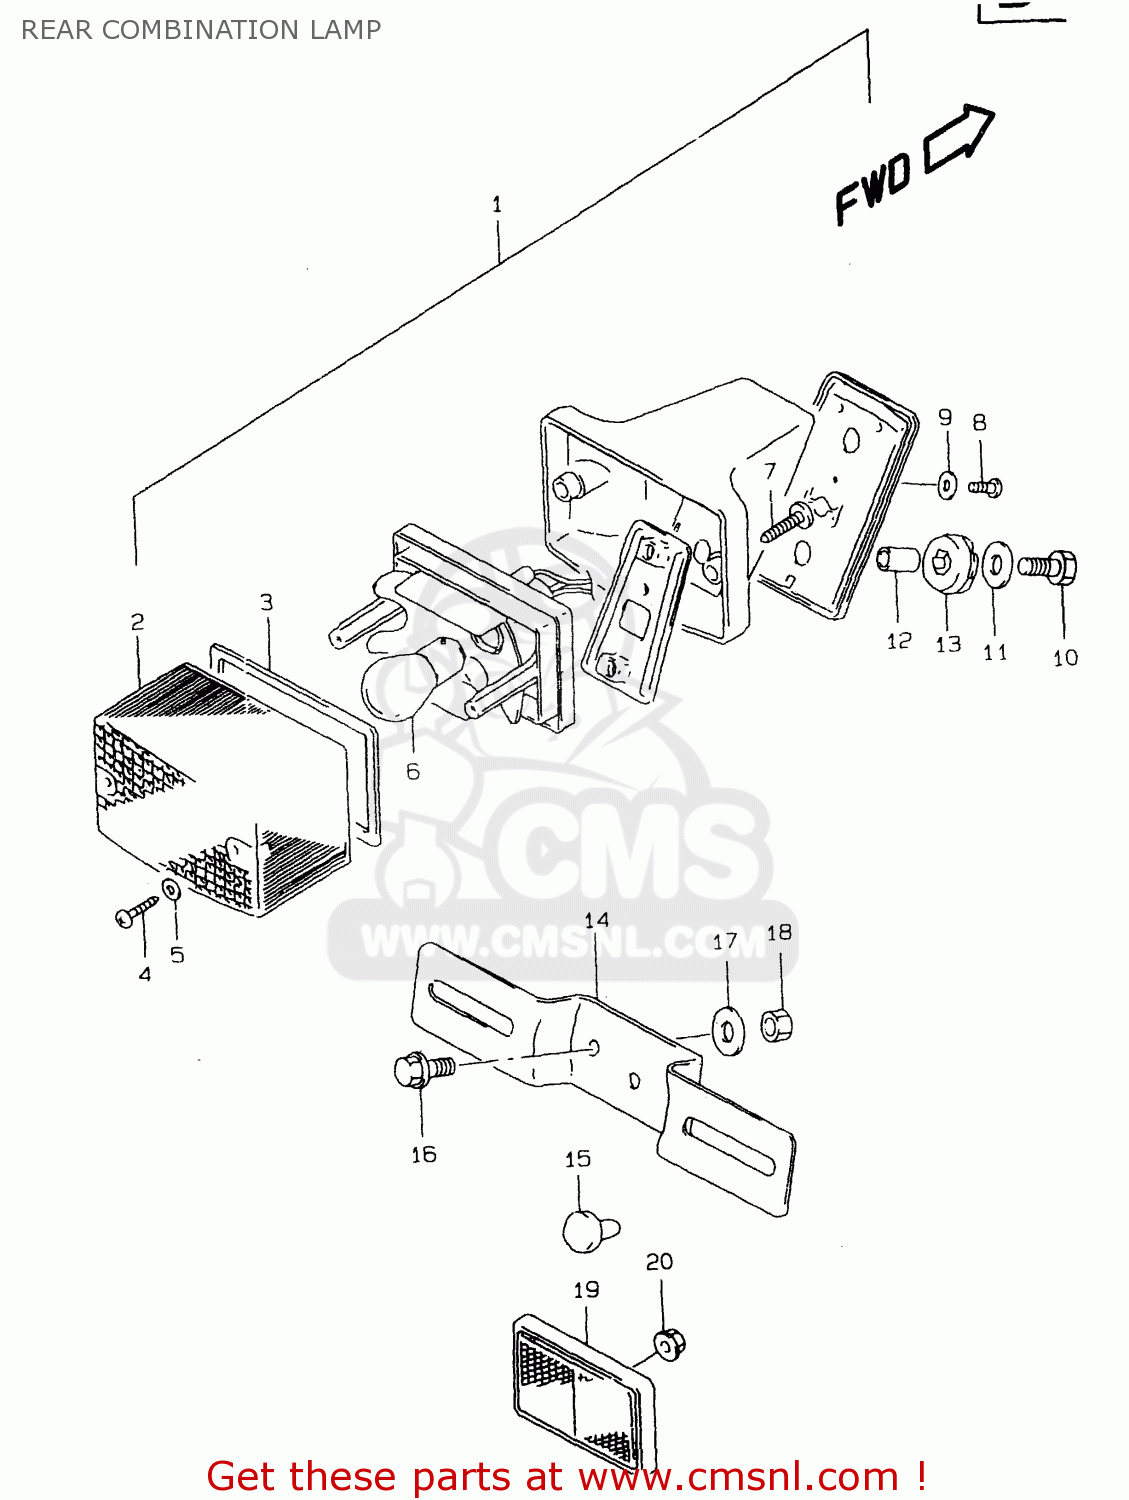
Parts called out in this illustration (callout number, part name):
1	LAMP ASSY,RR COMBINATION
2	LENS
3	GASKET,RR COMBI LAMP LENS (NAS)
4	SCREW
5	GASKET (NAS)
6	BULB(12V21/5W)
7	SCREW
8	SCREW
9	WASHER
10	BOLT
11	WASHER
12	SPACER(6.5X9X17.5)
13	CUSHION
14	BRACKET,LICENSE PLATE
15	CUSHION
16	BOLT
17	WASHER
18	NUT 6MM
19	RR ASSY,RR
20	NUT
